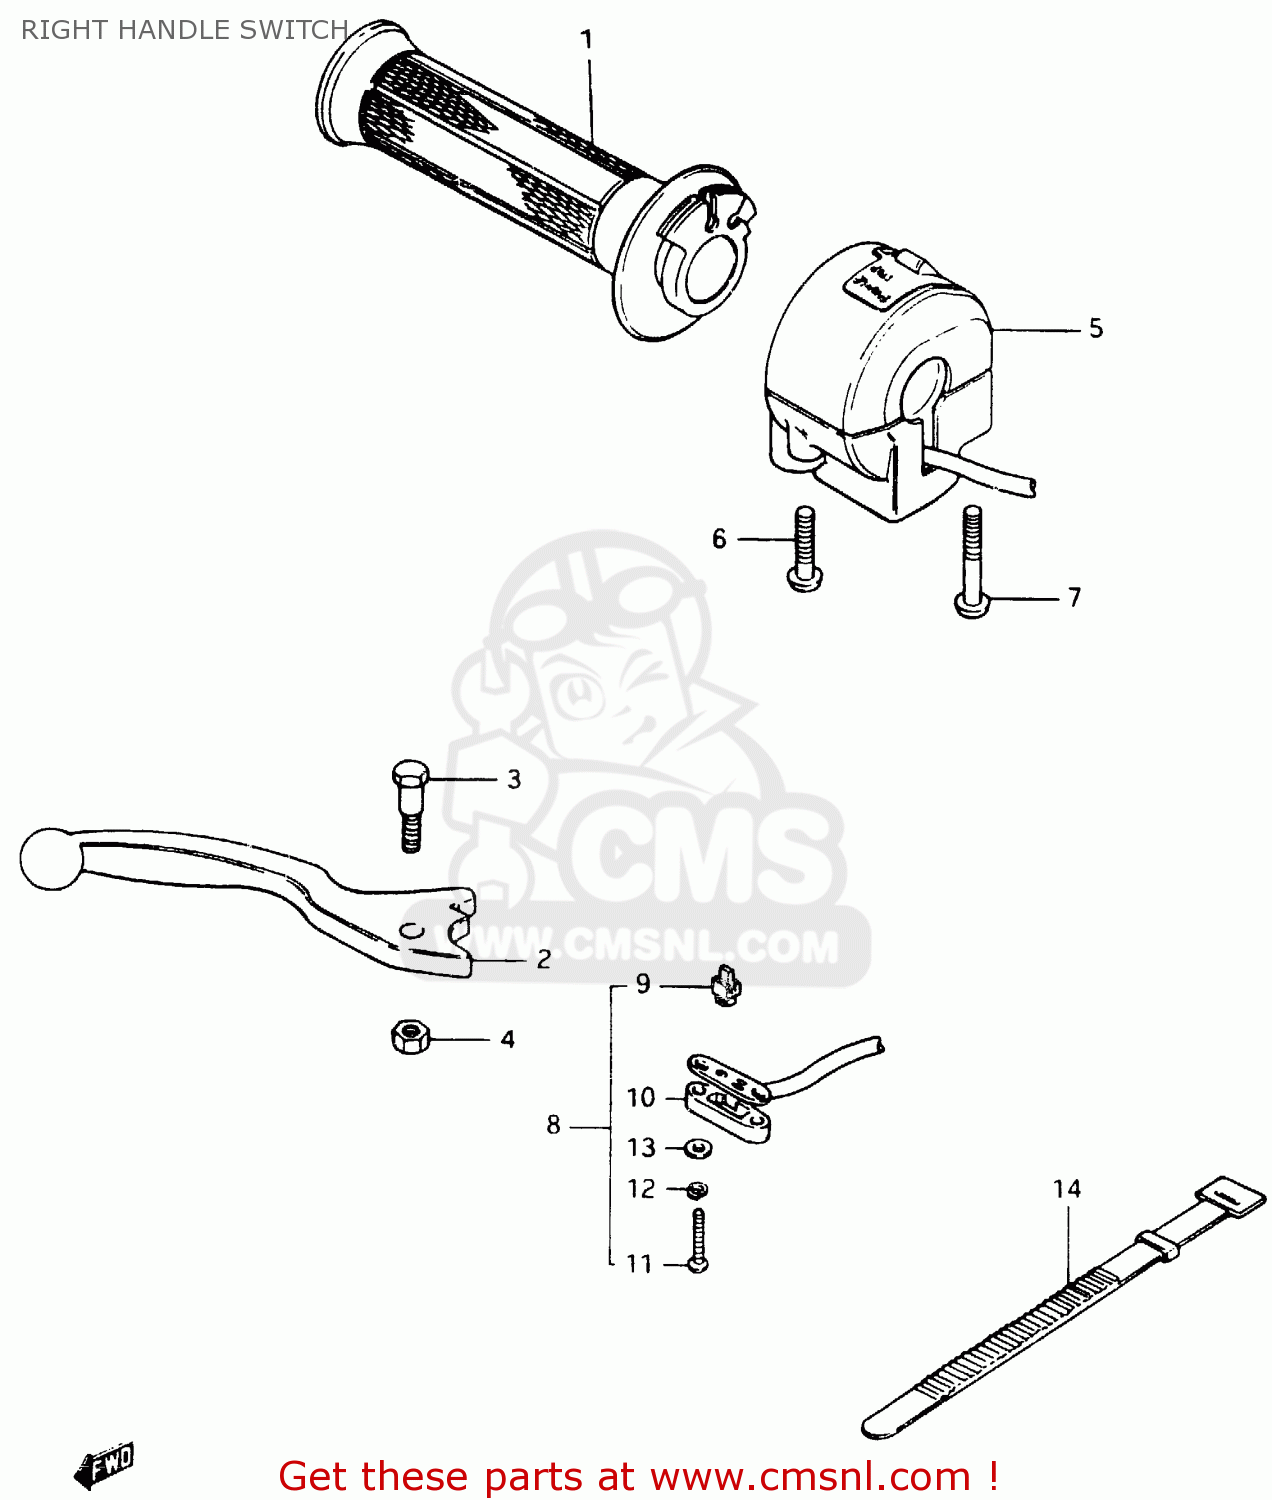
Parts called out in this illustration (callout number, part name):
1	GRIP,THROTTLE
2	LEVER,BRAKE
3	BOLT
4	NUT 6MM
5	SWITCH ASSY, HANDLE LH
6	SCREW
7	SCREW
8	SWITCH ASSEMBLY
9	CONTACT,SWITCH
10	COVER,FR BK TERMINAL BASE
11	SCREW
12	LOCK WASHER
13	WASHER
14	CLAMP(L:120)
